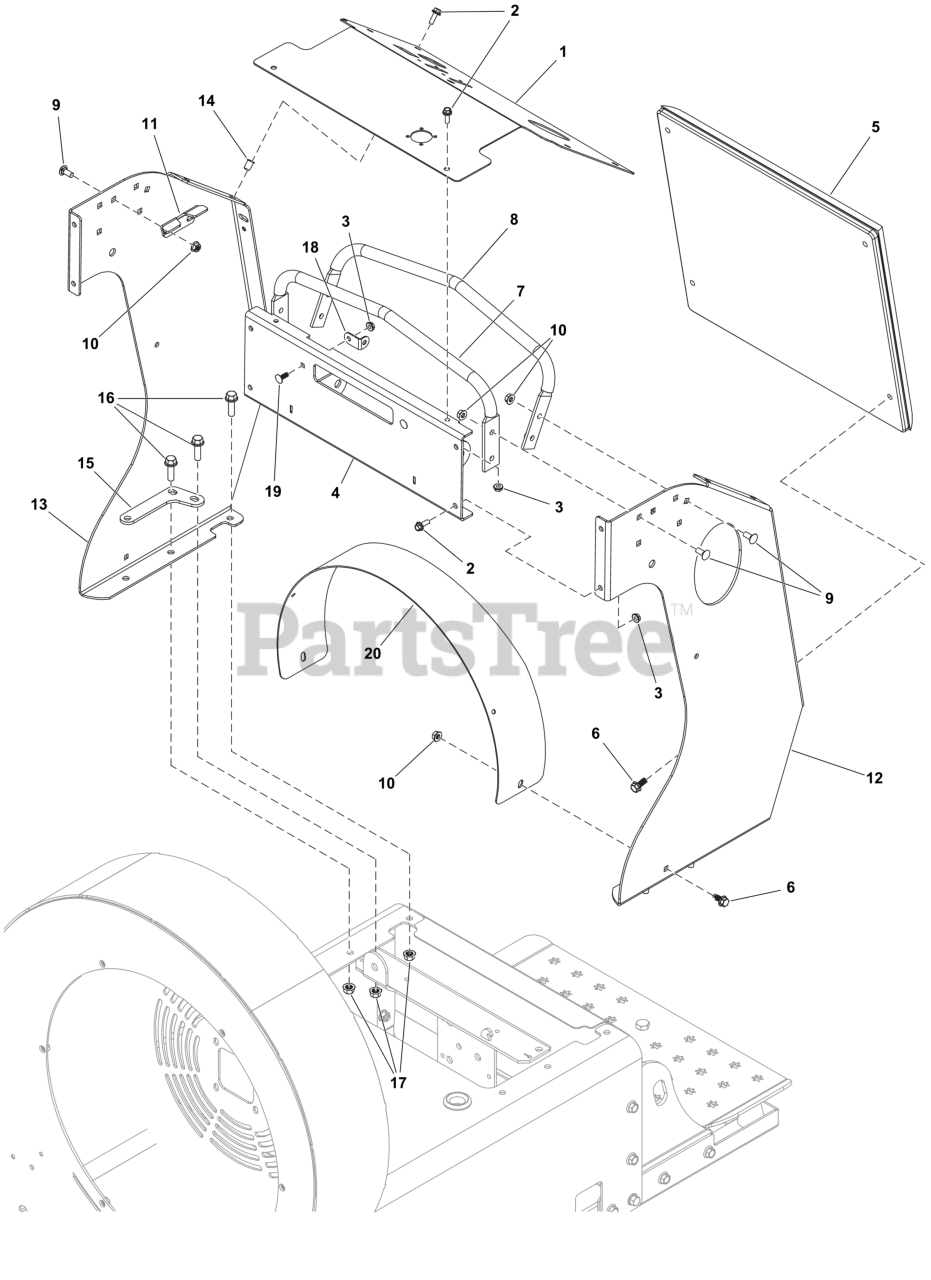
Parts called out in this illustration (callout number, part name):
1	PLATE, Control Panel
5	PAD, KNEE
6	SCREW, 5/16-18
7	HANDLE, FRONT
8	HANDLE, REAR
9	BOLT, 5/16-18 X 3/4",
10	NUT, 5/16-18 HEX SERR
12	CONTROL, Tower
13	CONTROL, TOWER
16	BOLT
18	BRACKET, L Headlight Mount
19	BOLT, 1/4-20X.750, SQ
20	GUARD, Belt
